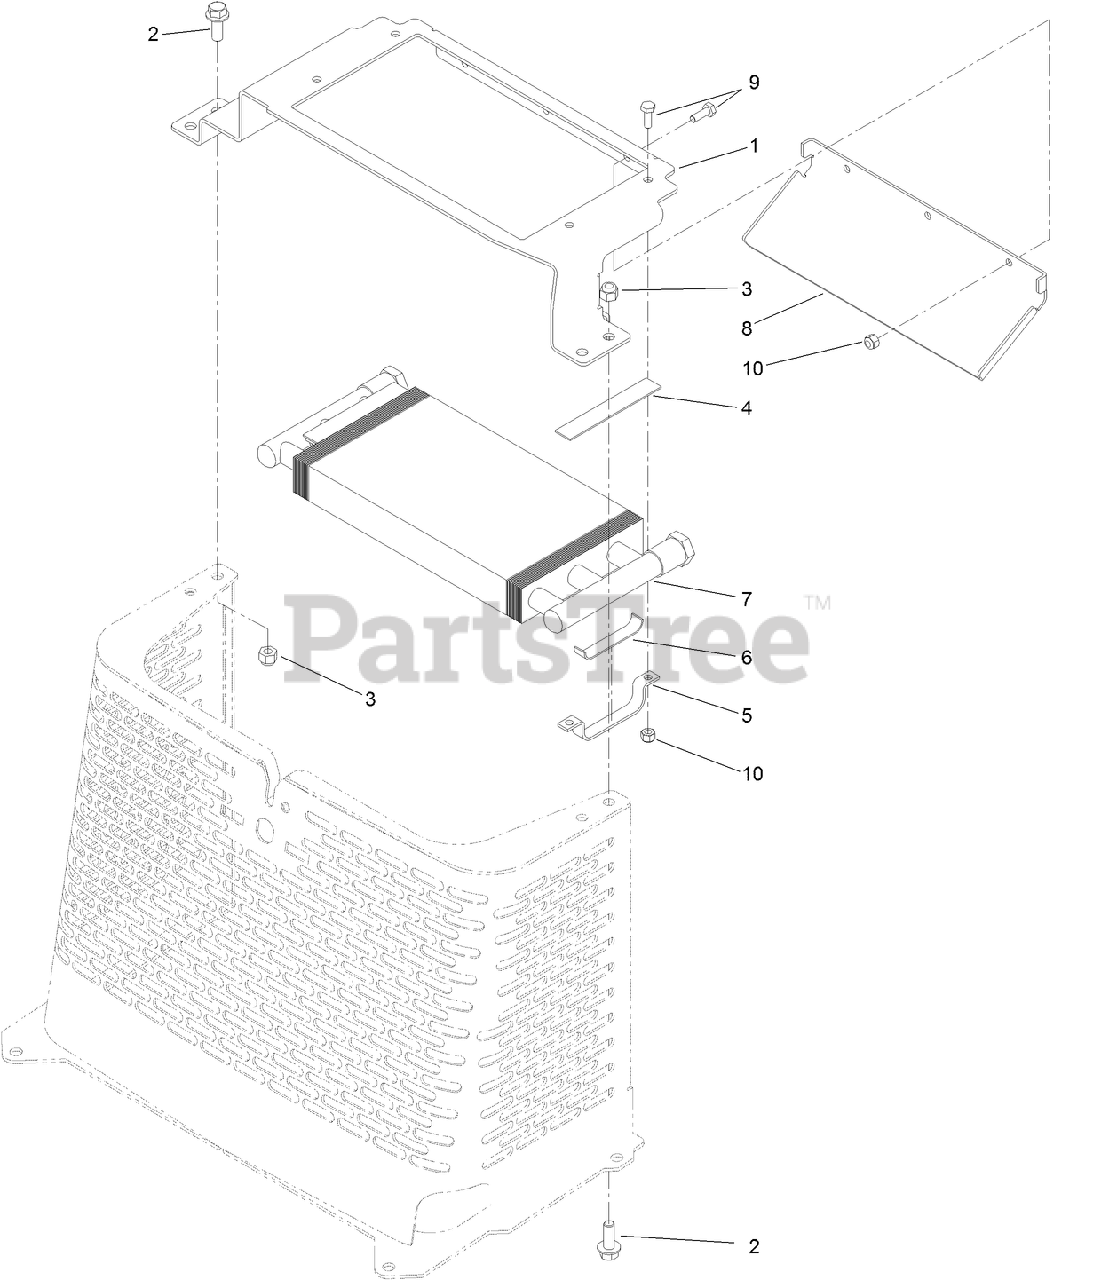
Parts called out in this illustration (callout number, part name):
1	BRACKET-MOUNTING, COOLER
2	SCREW-HHF
3	NUT-LOCK, NI
4	PAD-FOOTREST
5	SUPPORT-COOLER
6	PAD-SUPPORT
7	EXCHANGER-HEAT
8	DEFLECTOR-COOLER
9	SCREW-HH
10	NUT-LOCK, NI
